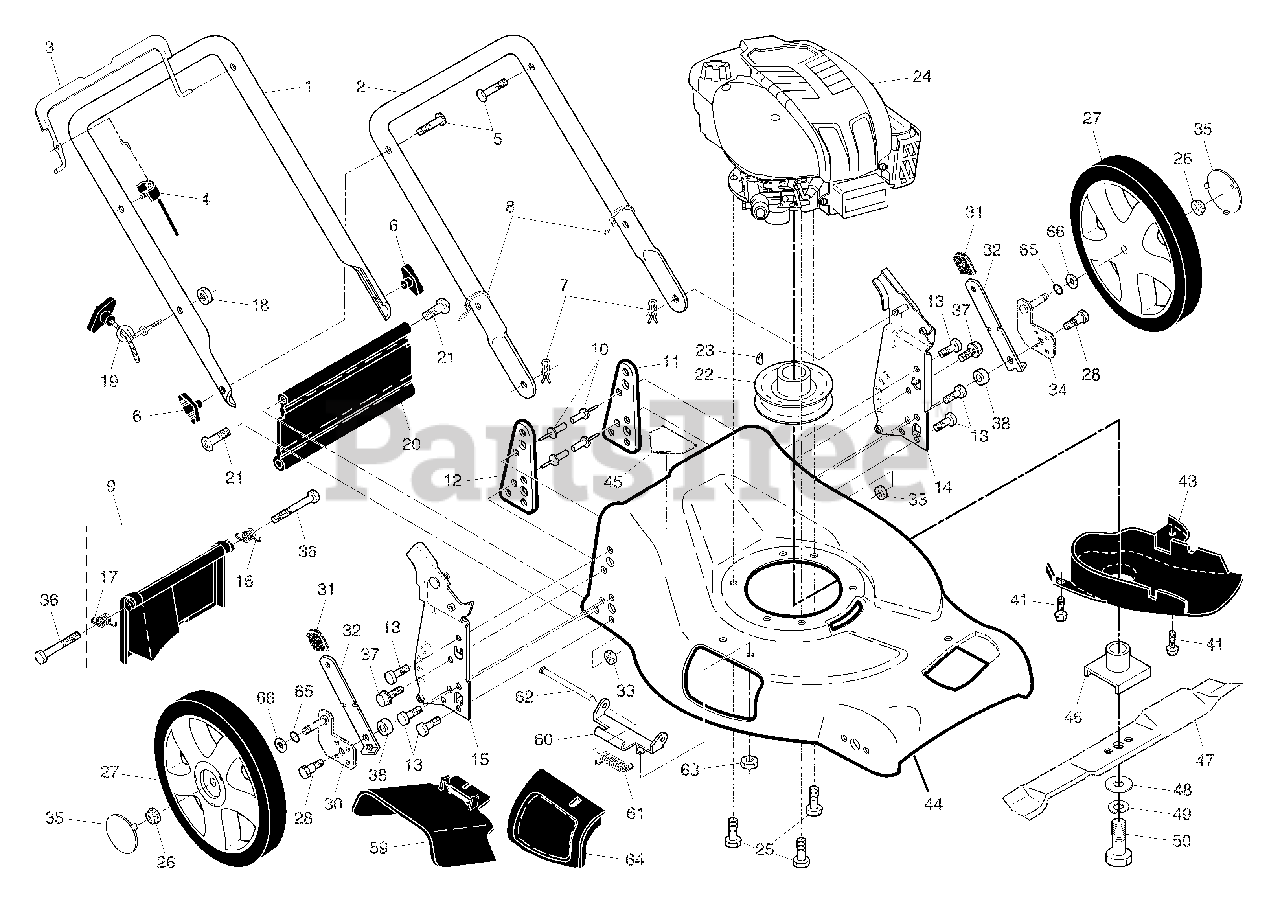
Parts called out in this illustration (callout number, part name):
1	Upper Handle
2	Lower Handle
3	Control Bar
4	Engine Zone Control Cable
5	Handle Bolt
6	Handle Knob
7	Hairpin Cotter
8	Wire Tie
9	Kit, Rear Door
11	Support Bracket, LH
12	Support Bracket, RH
13	Screw 1/4-20 x 5/8
14	Handle Bracket Assembly, LH
15	Handle Bracket Assembly, RH
16	Spring, Rear Door, LH
17	Spring, Rear Door, RH
18	Nut, Hex
19	Rope Guide
20	Rear Skirt
21	Hinge Screw 1/4-20 x 1-1/4
22	Engine Pulley
23	Hi-Pro Key
25	Screw, Hex Head, Threaded, Rolled 3/8-16 x 1-1/8
26	Nut, Hex, Flanged
27	Wheel Assembly, Rear
28	Shoulder Bolt 5/16-18 x .33
30	Axle Arm Assembly, Rear, RH
31	Selector Knob
32	Selector Spring
34	Axle Arm Assembly, Rear, LH
35	Hubcap
37	Thread Cutting Screw w/Sems 5/16-18 x 3/4
41	Screw, Debris Shield
43	Debris Shield
44	Kit, Lawn Mower Housing
45	Danger Decal
46	Blade Adapter
47	Blade, 21"
48	Hardened Washer
49	Helical Washer 3/8
50	Hex Head Machine Screw 3/8-24 x 1-3/8 Grade 8
59	Discharge Deflector
60	Hinge Bracket Assembly
61	Spring
62	Rod, Hinge
63	Locknut, Hex
64	Mulcher Door
65	O-Ring
66	Washer, Flat 3/8
